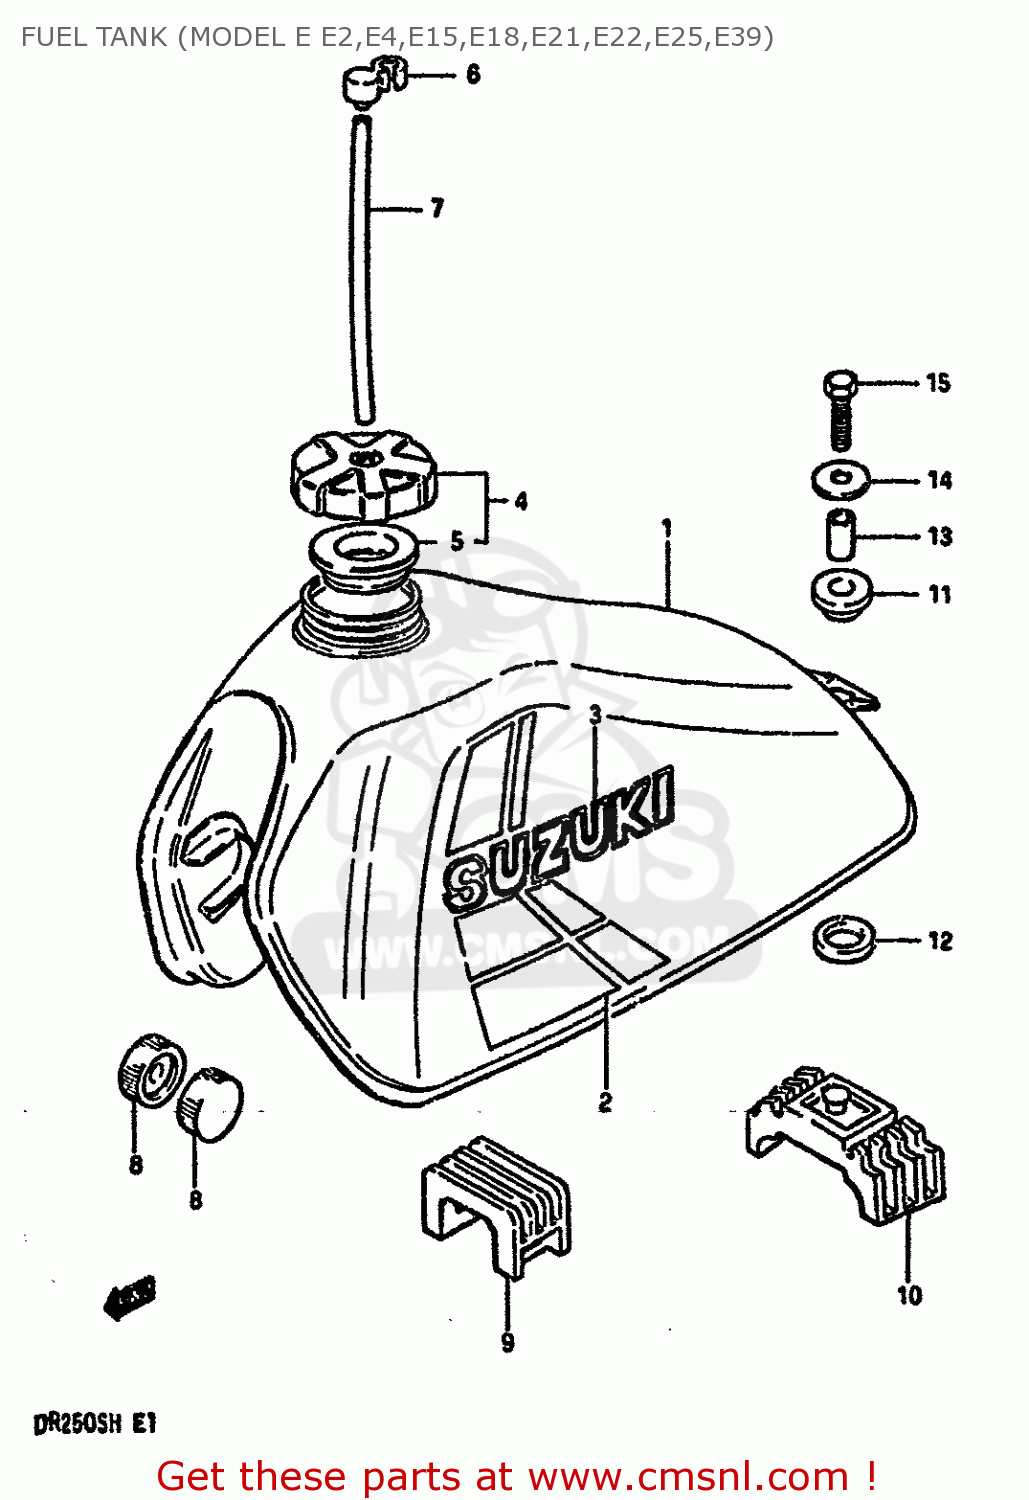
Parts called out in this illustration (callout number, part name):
1	TANK ASSY,FUEL (RED)
2	TAPE SET,FUEL TANK
3	EMBLEM
4	CAP SET,FUEL TANK
5	GASKET (NAS)
6	CLAMP,FUEL TANK BREATHER HOSE
7	HOSE
8	CUSHION
9	CUSHION,TANK UPR FR
10	CUSHION,FUEL TANK,REAR
11	CUSHION
12	CUSHION
13	SPACER(8.5X12X19)
14	WASHER (8.5X29X1.6)
15	BOLT
